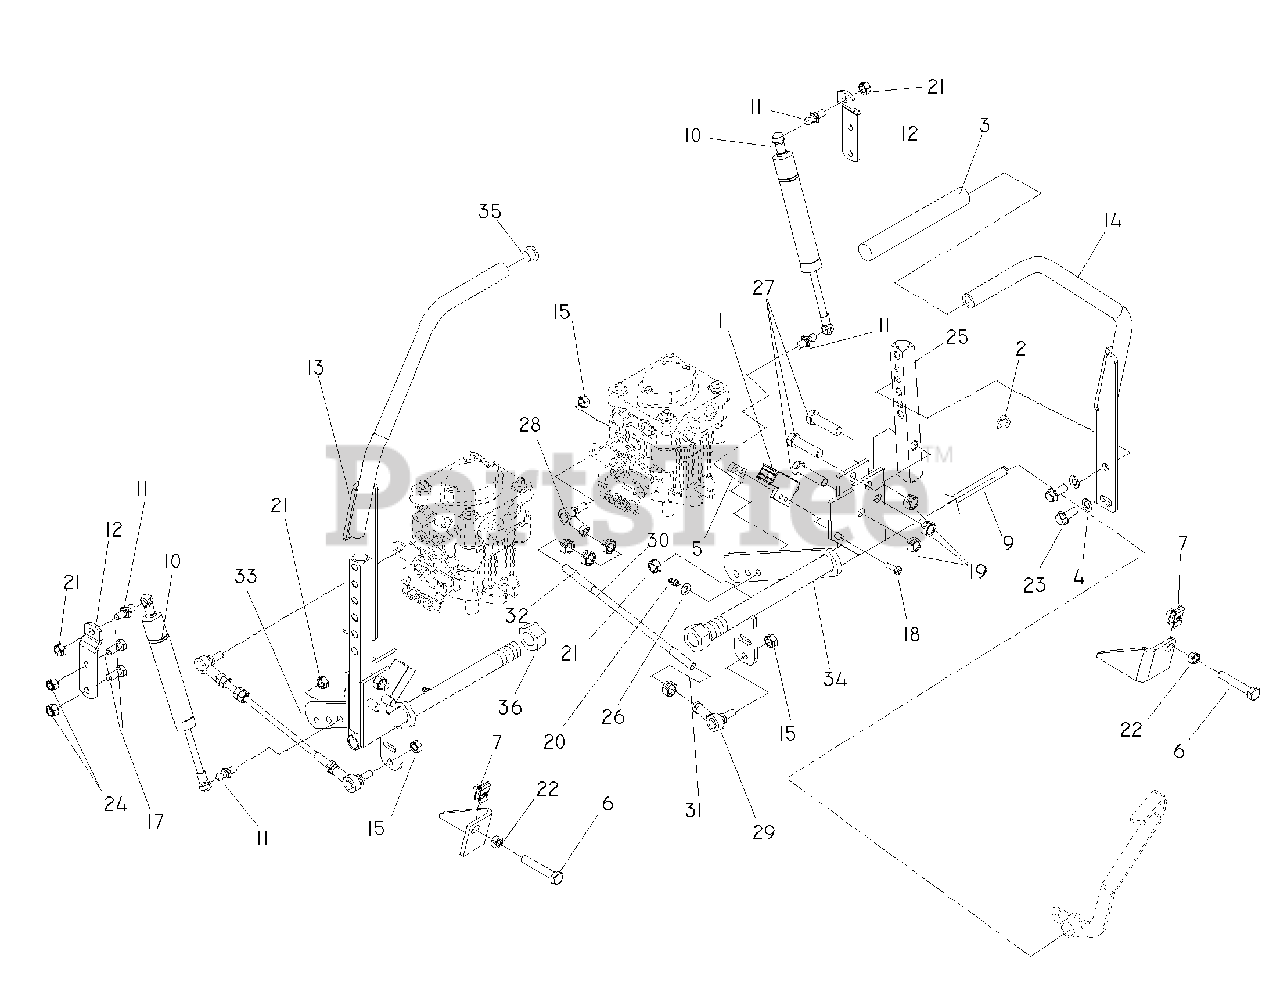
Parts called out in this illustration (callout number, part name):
1	SWITCH, INTERLOCK
2	E-RING 1/2 (2 2)
3	GRIP, FOAM (GROUND) 15
4	WASHER, 3/8 DISC SPRING SPEC
5	TAPPED PLATE
6	HCS 5/16C X 1 1/4
7	U-CLIP 5/16-18 NUT RETAINER
9	CONTROL SHAFT
10	DAMPENER
11	STUD.BALL.10MM
12	DAMPENER ARM
13	LEVER, DRIVE, RT
14	LEVER, DRIVE, LT
15	NUT 5/16F NYLOC
17	HCS 5/16C X 3/4
18	SCREW #10-24 X 5/8
19	NUT 3/8-16 NYLOC
20	ZERK
21	NUT 5/16C CENTERLOCK
22	NUT 5/16C HEX
23	HCS 3/8C X 1
24	NUT 5/16 NYLOC
25	CONTROL ARM
27	HCS 3/8-16 X 1 3/4 GR5
28	SPHERICAL ROD END, RH
29	SPHERICAL ROD END, LH
30	PUMP CONTROL LINK
31	NUT 5/16F LEFTHAND
32	NUT 5/16F
33	CONTROL-DRIVE RT
35	END PLUG 15/16` (BLACK)
36	NUT 3/4 X 16 HEX CTR
